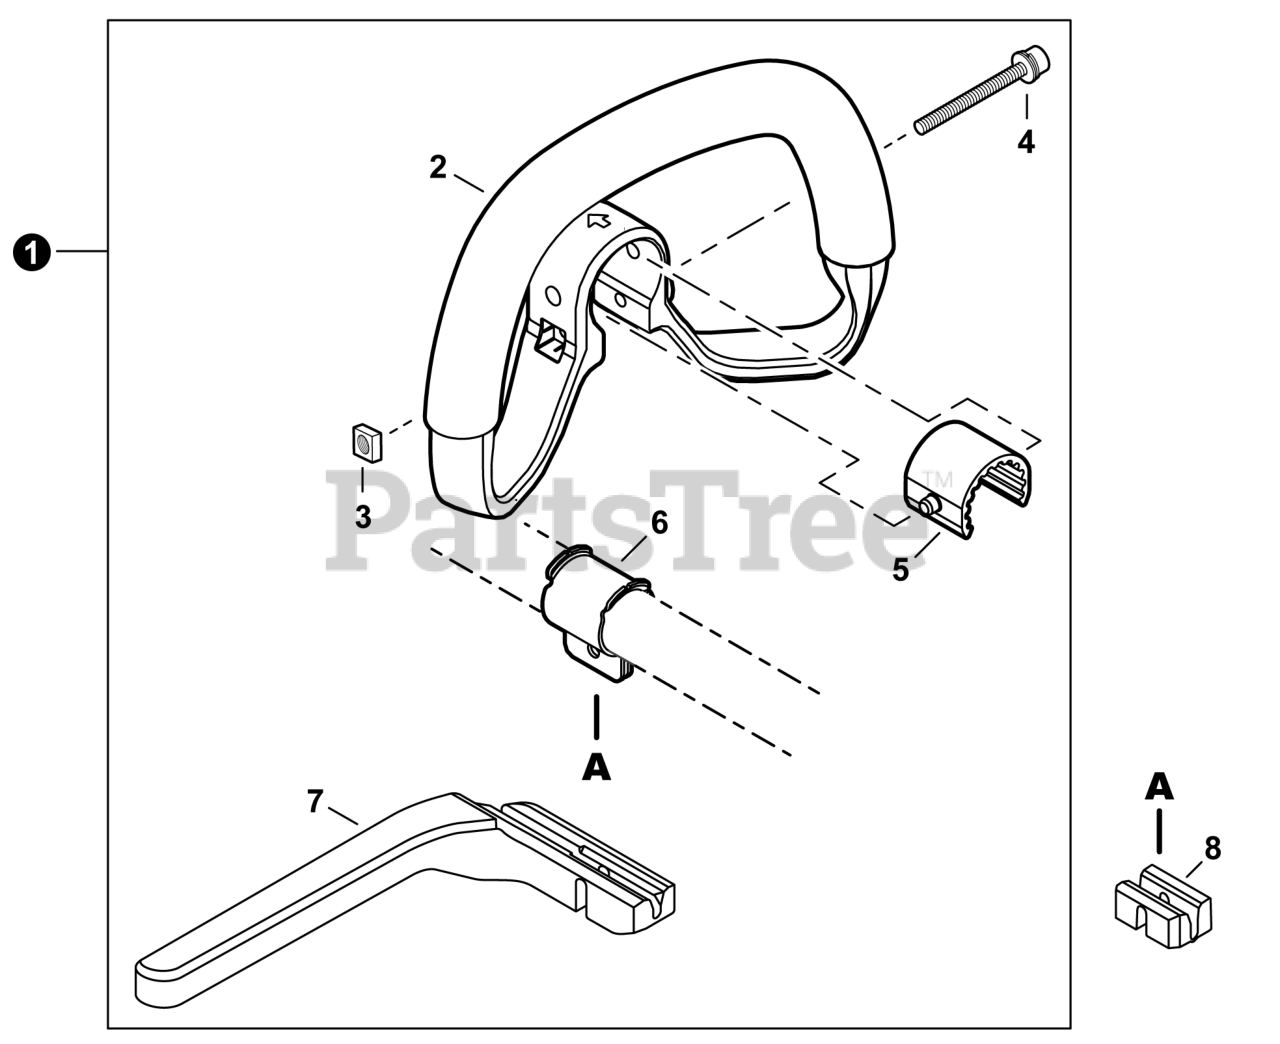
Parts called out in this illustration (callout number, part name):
1	HANDLE ASSY, SUPPORT
2	HANDLE, SUPPORT
4	BOLT 5×45
5	CUSHION
6	BRACKET, MOUNTING
7	BAR, BARRIER
